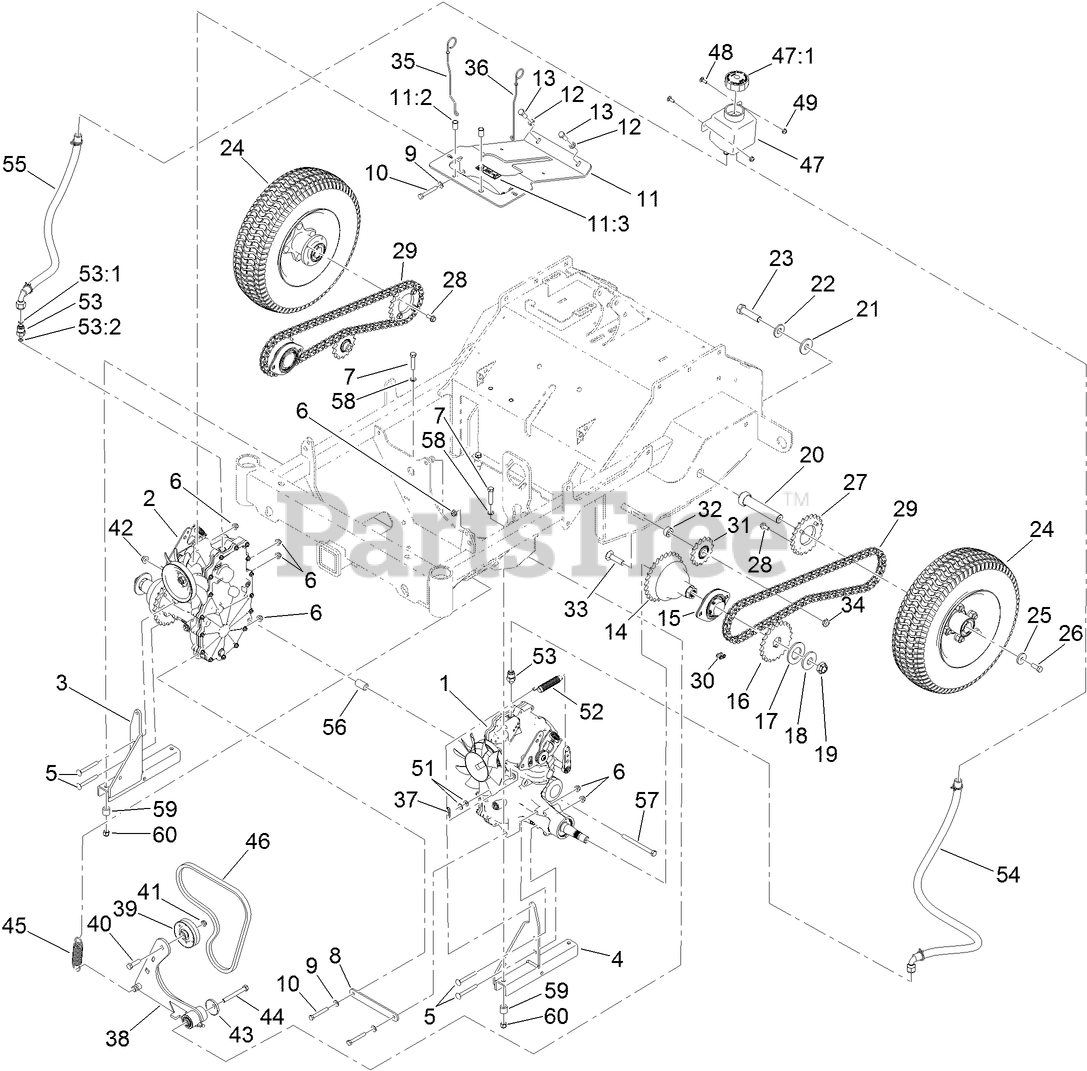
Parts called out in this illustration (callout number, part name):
1	HYDRO-ZT3100, LH
2	HYDRO-ZT3100, RH
3	MOUNT-HYDRO, RH
4	MOUNT-HYDRO, LH
5	SCREW-CARR
6	NUT-HF, NI
7	SCREW-HH
8	CROSSMEMBER-TRANSMISSION
9	WASHER-SPRING
10	SCREW-HH
11	SUPPORT-COVER
11:2	NUT-CLINCH
11:3	DECAL-DANGER
12	WASHER-LOCK
13	SCREW-HH
14	HUB-BELL
15	BEARING-FLANGED
16	SPROCKET
17	WASHER-SPACER
18	WASHER-BELLEVILLE
19	NUT-LOCK
20	AXLE-WHEEL, DRIVE
21	WASHER-SPACER
22	WASHER-BELLEVILLE
23	SCREW-HH
24	WHEEL AND TIRE ASM
25	WASHER-FLAT
26	SCREW-HH, LOCK
27	SPROCKET
28	SCREW-HHF
29	CHAIN-ROLLER
30	LINK-CONNECTING
31	SPROCKET-IDLER, 15T
32	SPACER
33	SCREW-CARR
34	NUT-HEX
35	ROD-BYPASS, LH
36	ROD-BYPASS, RH
38	IDLER ARM ASM
39	PULLEY-IDLER
40	SCREW-HH
42	NUT-HF, NI
43	GUARD-TOP
44	SCREW-HH
45	SPRING-EXTENSION
46	BELT-V, COGGED
47	TANK-HYD
47:1	CAP-RESERVOIR, HYD
48	BOLT-CARR
49	NUT-HF
51	WASHER
52	SPRING-EXTENSION
53	FITTING-STRAIGHT
53:1	O-RING
53:2	O-RING
54	HOSE ASM
55	HOSE ASM
56	SPACER
57	SCREW-HH
58	SPACER-BRAKE, PARKING
59	SPACER
60	NUT-LOCK
